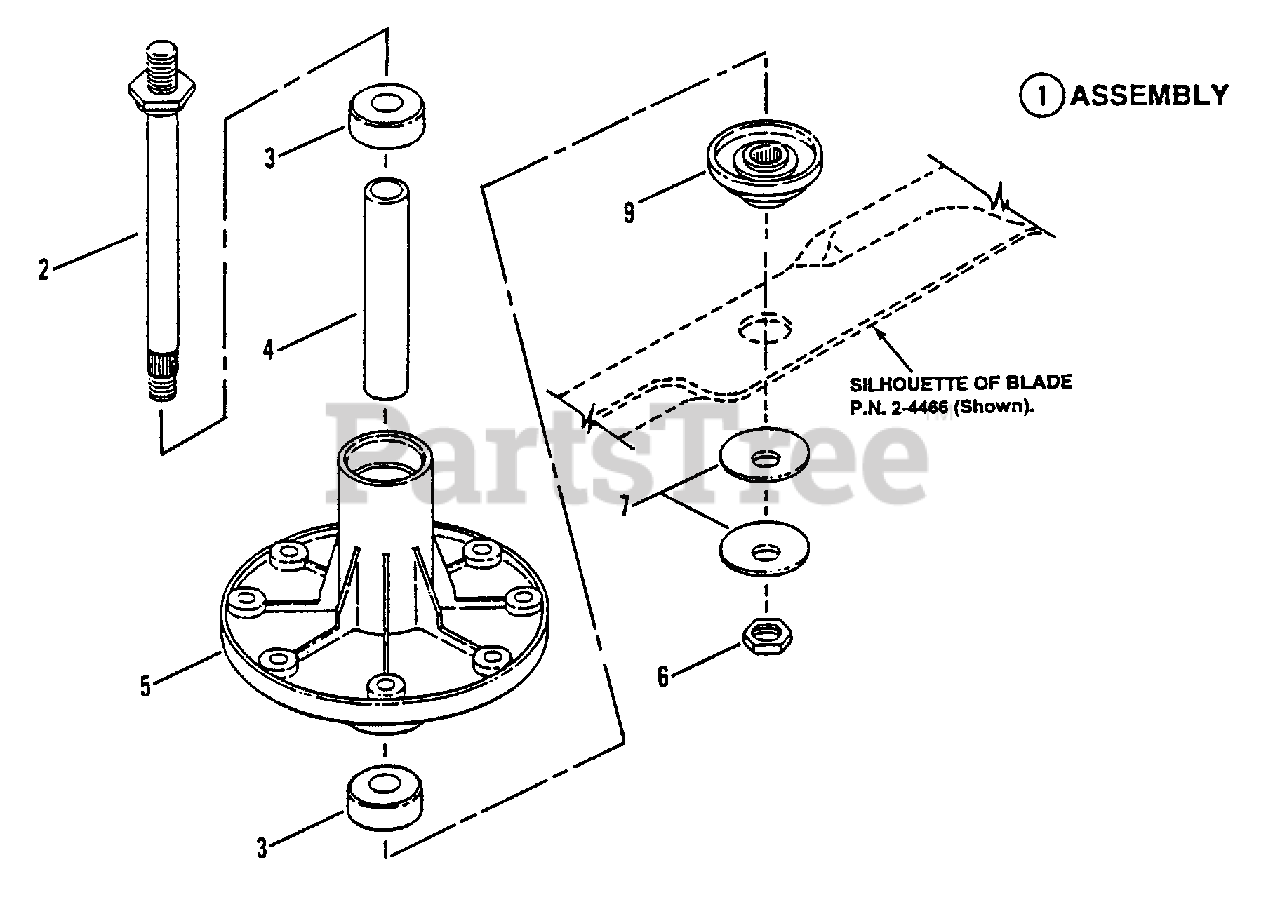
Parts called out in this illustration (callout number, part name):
1	ASSEMBLY, Spindle Housing
2	SPINDLE 7.019" Long
3	BEARING, Spindle 17MM
4	SPACER, Spindle Housing .875 OD X .687 ID X 3.79 L
5	HOUSING, Spindle 4.78" Tall
6	NUT, 9/16-18 Hex Jam
7	WASHER, Belleville .594 x 1.75
9	SPACER, Blade
